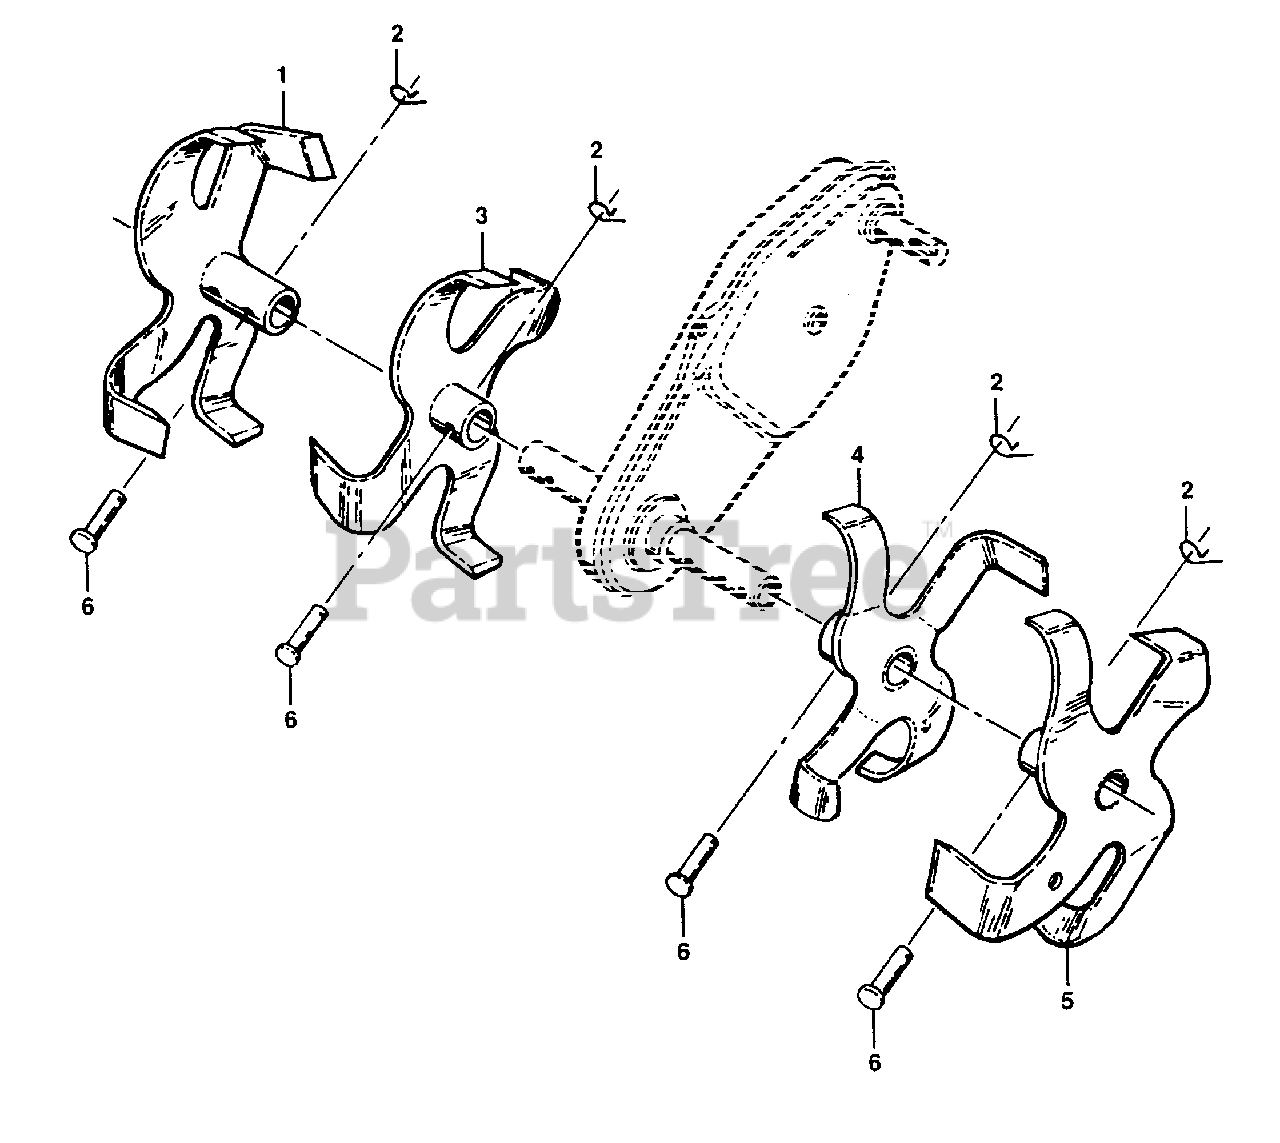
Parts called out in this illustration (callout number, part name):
1	Tine, Outer, R.H. (AYP part number)
2	Clip, Hairpin (AYP part number)
3	Tine, Inner, R.H. (AYP part number)
4	Tine, Inner, L.H. (AYP part number)
5	Tine, Outer, L.H. (AYP part number)
6	Pin, Clevis (AYP part number)
